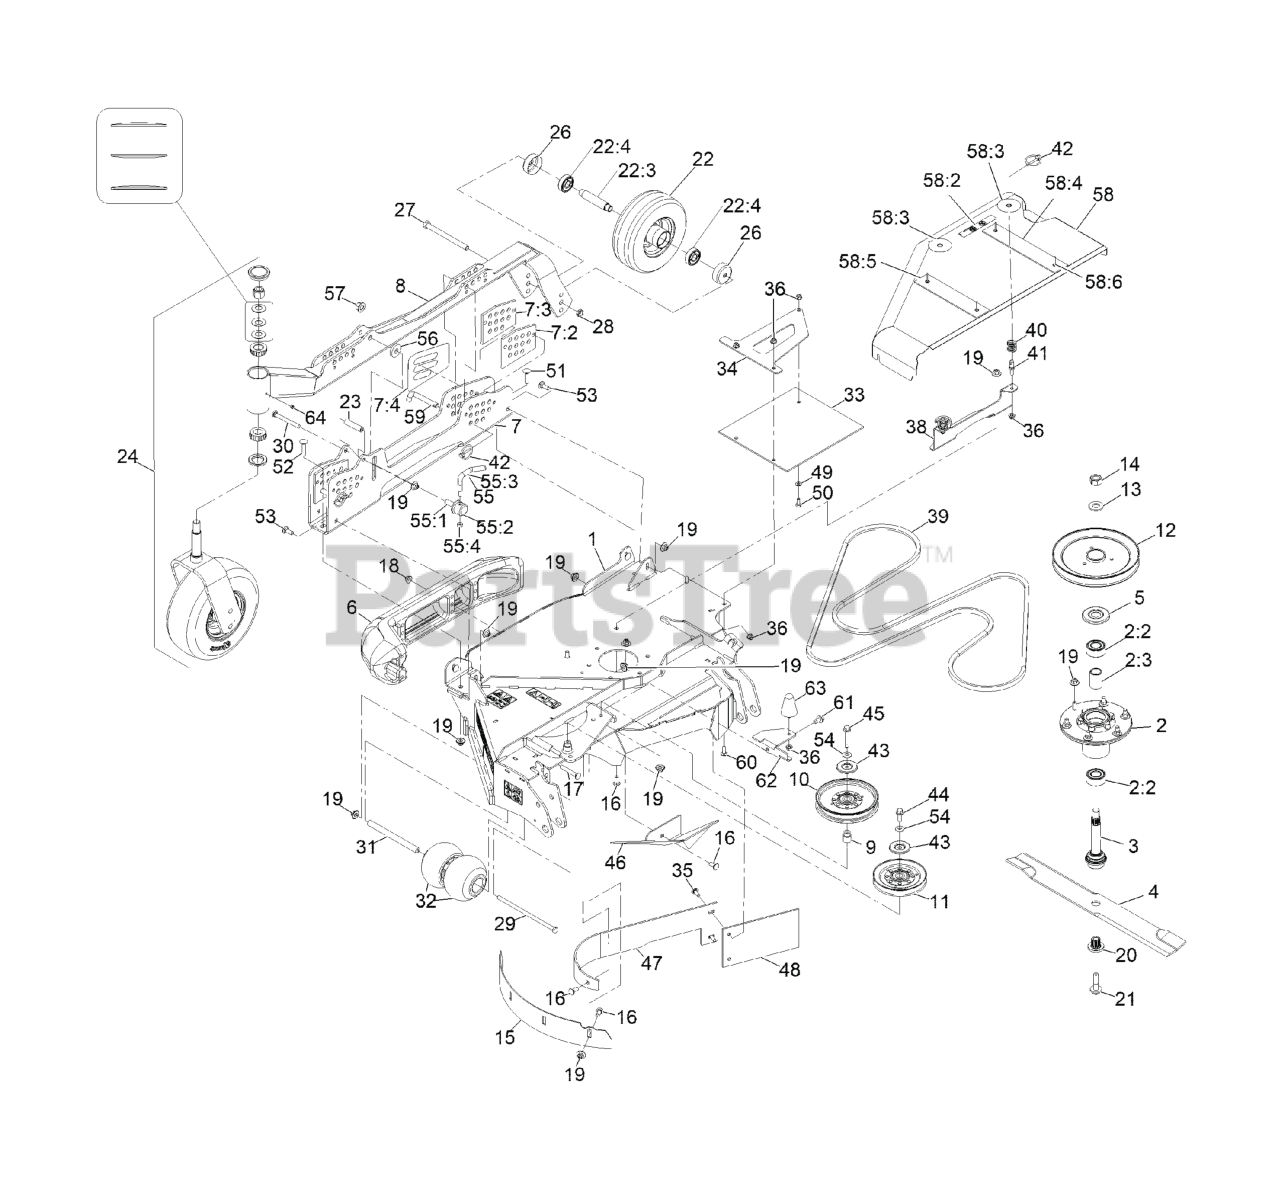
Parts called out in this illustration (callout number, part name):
1	ASM-DECK, RH WING 96
2	ASM-CUTTER HSG
2:2	BEARING-3205 TRASHGUARD
2:3	SPACER-BEARING
3	ASM-SPINDLE AND SEAL
5	GUARD-BEARING, TOP
6	SKID-BUMPER, DECK
7	RH HOC CHANNEL ASM
7:2	PLATE-GUIDE, HOC (LH)
7:3	PLATE-GUIDE, HOC (RH)
7:4	DECAL-HEIGHT OF CUT, RH
8	CALL CUSTOMER SERVICE
9	BUSHING-IDLER
10	IDLER-PULLEY
11	IDLER-V
12	SHEAVE-SINGLE 96RD
14	NUT-HEX
15	BAFFLE-DEPTH, RH
16	BOLT-CARR
17	SCREW-CARR
18	NUT-HF, NI
19	Nut-Nyloc 3/8-16 Flg
20	BUSHING,SPLINED
21	SCREW,SEMS 1/2-20 X 2.19
22	WHEEL AND TIRE ASM
22:3	AXLE-CASTER
22:4	BEARING
26	GUARD, SEAL
27	SCREW-HH
28	NUT-HEX
29	SCREW-HH
30	SCREW-CARR
31	SPACER-WHEEL
32	ROLLER-SCALP, ANTI
33	GUARD-TIRE
34	SUPPORT-FLAP, RH
35	SCREW-CARR
36	NUT-HF, NI
38	BRACKET-SHIELD MOUNT, OUT
41	PIN, SPRING
42	PIN-LYNCH
43	SHIELD-DUST
44	SCREW-HHF 3/8-16 X 1
45	SCREW-HHF
46	BAFFLE-DEFLECT, RH
47	BAFFLE-DOGLEG, RH
48	FLAP-RUBBER
49	WASHER-PLAIN
50	SCREW-HH
51	SCREW-CARR
52	SCREW-CARR
53	BOLT-CARR
54	WASHER-BELLEVILLE
55	LEVER ASM
55:1	SCREW-LOCK
55:2	CAP-LOCK
55:4	NUT-LOCK, NI
57	Nut-Lock 1/2-13
58	ASM-Wing Shield RH
58:2	DECAL-NO STEP
58:3	DECAL-SCRATCH COVER
58:4	Plate-Uhmw 2"
58:5	PLATE-FRONT
58:6	Rivet-Pop
59	PIN-HOC
60	BOLT-CARR
61	SCREW-HWH
62	BRACKET-COVER RETAINER
63	BUMPER-RUBBER
